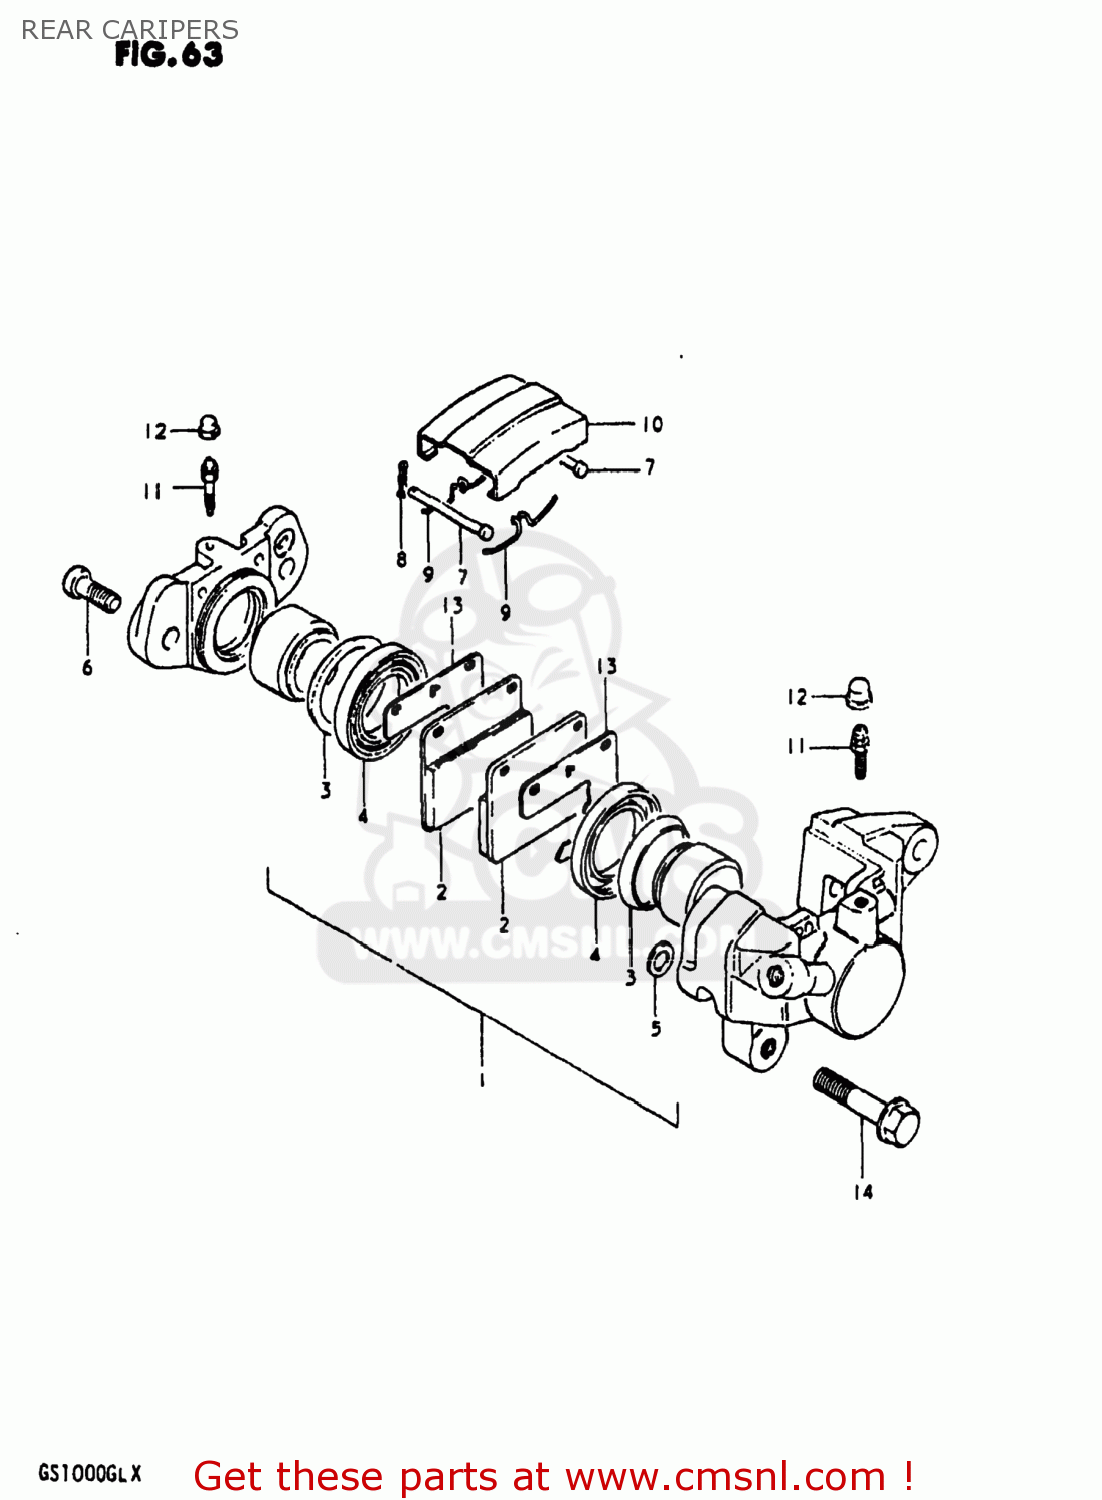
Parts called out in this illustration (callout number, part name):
1	PISTON SET
2	PAD,BRAKE
3	SEAL,PISTON
4	BOOT,PISTON
5	SEAL,PISTON
6	BOLT,HOUSING
7	PIN,PAD
8	CLIP,PAD PIN
9	SPRING
10	COVER,DUST
11	BLEEDER
12	CAP,BREATHER
13	SHIM,RR CALIPER
14	BOLT
